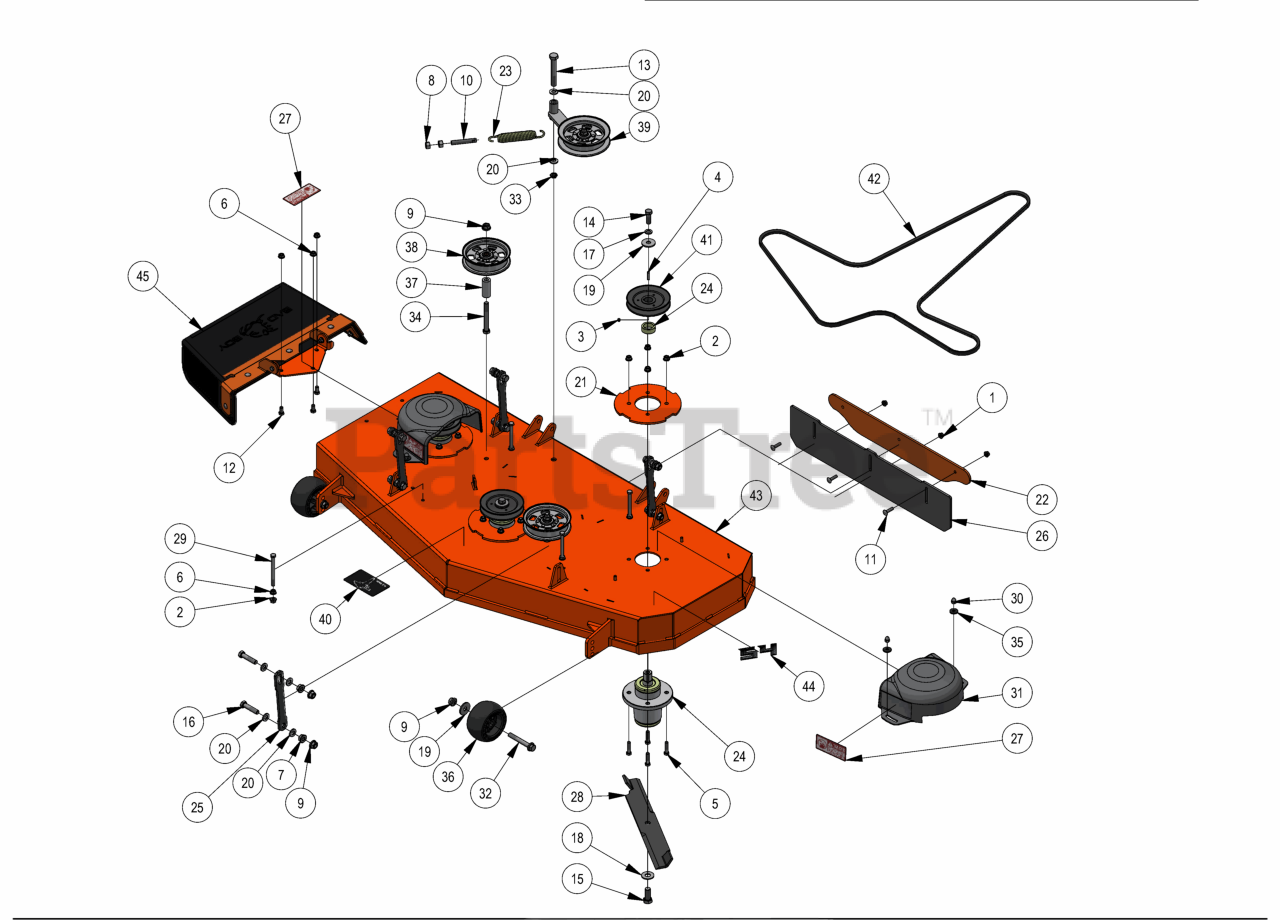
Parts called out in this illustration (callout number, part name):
1	5/16-18 NYLON INSERT FLANGE LOCKNUT ZINC
2	3/8-16 NYLON INSERT FLANGE LOCKNUT (GR.F) ZINC
3	5/16-24 X 1/4 SOCKET SET SCREW (CUP PT) PLAIN
4	1/4 X 1 SQ MACHINERY KEY 1018 STL PLN
5	3/8-16 X 1-1/2 HEX CAP SCREW (GR.5) ZINC
6	3/8-16 HEX SERRATED FLANGE NUT HARD/ZINC
7	1/2-13 HEX SERRATED FLANGE NUT HARD/ZINC
8	1/2-13 HEX NUT ZINC
9	1/2-13 NYLON INSERT FLANGE LOCKNUT ZINC
10	All Thread
11	5/16-18 X 1-1/4 CARRIAGE BOLT ZINC
12	3/8-16 X 3/4 HEX CAP SCREW (GR.5) ZINC
13	5/8-11 X 4 HEX CAP SCREW (GR.8) ZINC YELLOW
14	1/2"-20 x 1 1/2 - Grade 5 Fine Thread Bolt
15	5/8-18 X 1-1/2 HEX CAP SCREW (GR.8) ZINC YELLOW
16	1/2-13 X 2-1/4 HEX CAP SCREW (GR.5) ZINC
17	1/2 SPLIT LOCKWASHER (GR.8) ZINC/YELLOW
18	5/8 USS FLAT WASHER (1-3/4" OD) GR.8 ZINC YELLOW
19	1/2 BELLEVILLE WASHER (1-5/8 OD X .140 THK) ZINC
20	.505 ID X 1.000 OD X .125 THICK FLAT WASHER NYLON
21	Deck Spindle Support Plate
22	Striping Kit Plate
23	Deck Idler Spring
24	OUTLAW SPINDLE ASSEMBLY
25	23WB Deck Hanger
26	2023 MZ Stripping Kit Rubber
27	Danger Decal-Spindle/Discharge
28	54" Fusion Blade for Avenger/ZT/Mav/Outlaw/Revolt
29	3/8-16 X 4-1/4 HEX CAP SCREW (GR.5) ZINC
30	5/16-18 ACORN NUT HIGH-CROWN ZC
31	Pulley Cover
32	1/2-13 X 90MM HEX FLANGE BOLT W/SHOULDER (GR.8) ZINC
33	1/2-13 NYLON INSERT JAM LOCKNUT ZINC
34	1/2-13 X 4 HEX CAP SCREW (GR.8) ZINC YELLOW
35	.360 ID X .983 OD X .120 THICK FLAT WASHER NYLON BLACK
36	Deck Wheel
37	2019 Revolt Stationary Idle Spacer
38	5-3/4 Idler Pulley
39	2019 Revolt Deck Idler Assembly
40	2017 MZ Magnum 48"/42" Deck Route Decal
41	5.25" Deck Spindle Pulley
42	B128 Deck Belt
43	23WB 54in Deck
44	54" Deck Decal
45	Discharge Chute Assembly
